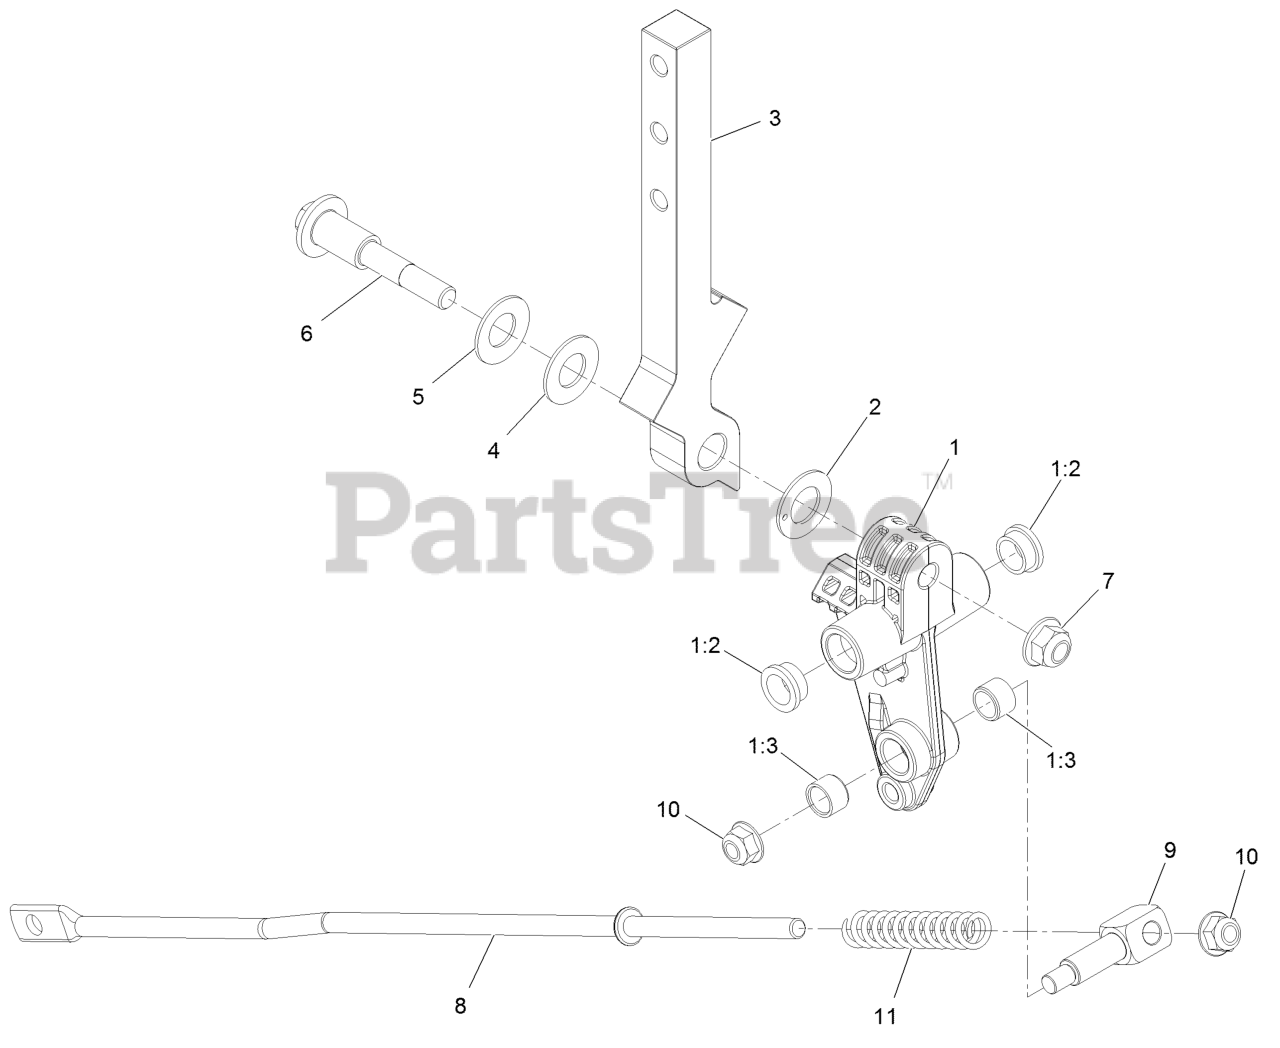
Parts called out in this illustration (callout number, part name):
1	CONTROL ARM ASM
1:2	BUSHING
1:3	BUSHING-SLEEVE
2	WASHER-FRICTION
3	ARM-CONTROL
5	WASHER-BELLEVILLE
6	BOLT-PIVOT
7	NUT-HF, NI
8	LINK-CONTROL
10	NUT-HF, NI
11	SPRING-RETURN, NEUTRAL
